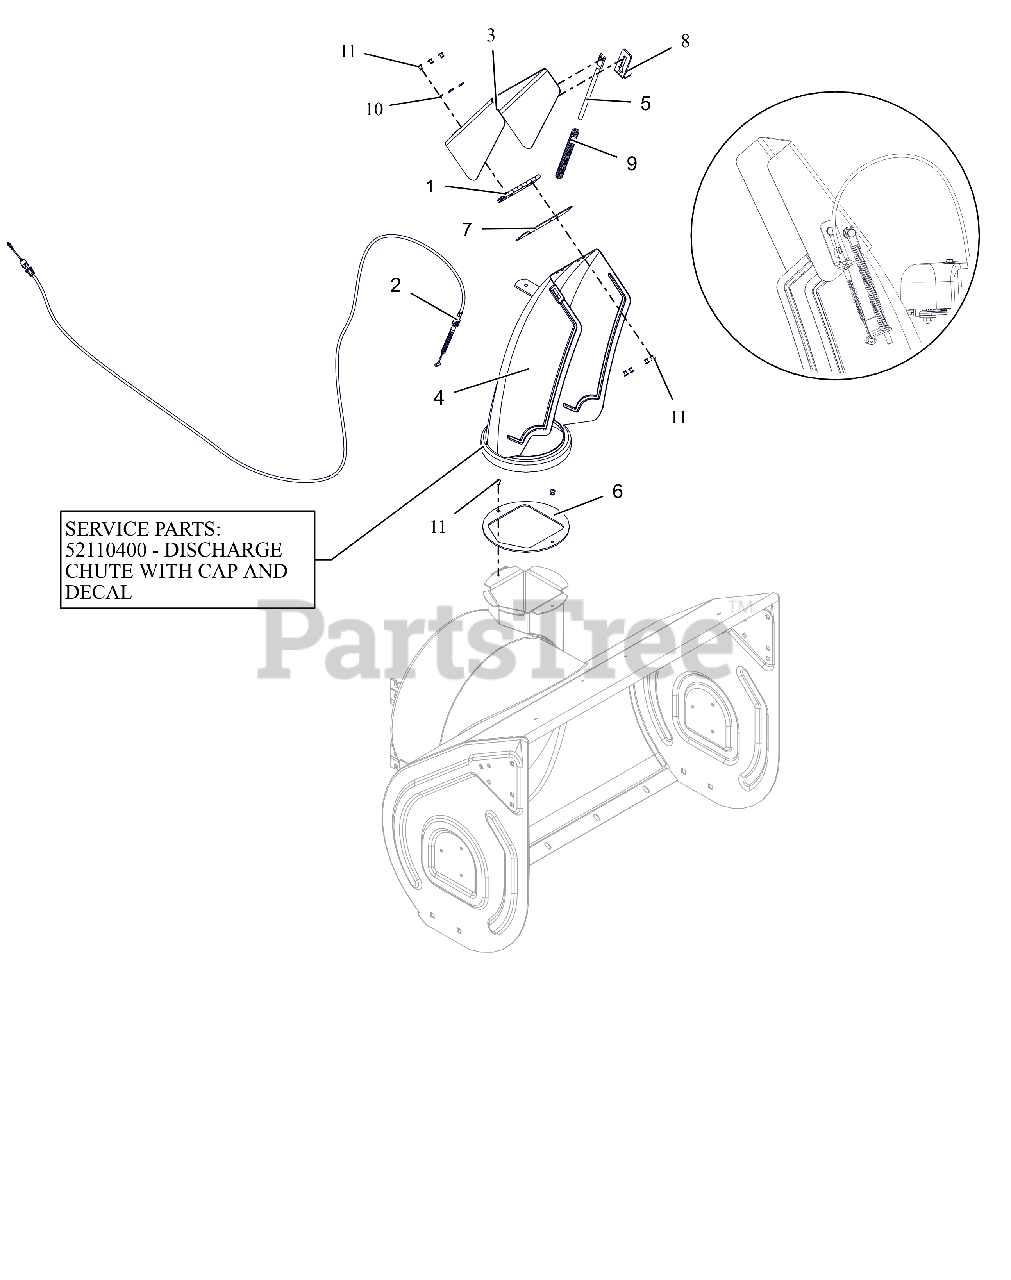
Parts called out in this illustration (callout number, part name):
2	CABLE, DEFLECTOR - DELUXE
3	CAP, LARGE REMOTE W/DECAL
4	CHUTE,DISCHARGE,NOTCHED,QT
4	CHUTE, DISCHARGE W/CAP
5	ROD, DEFLECTOR CAP
6	BAFFLE, DISCHARGE NECK
7	CAP SEAL 5.50
8	BRACKET, ANCHOR-CHUTE CABLE
9	SG-COMP .08X.40X6.50 14#/IN
10	WSHR,FLT .196X.500X.066 ZCC
11	RVT, POP .1875 ZCC
